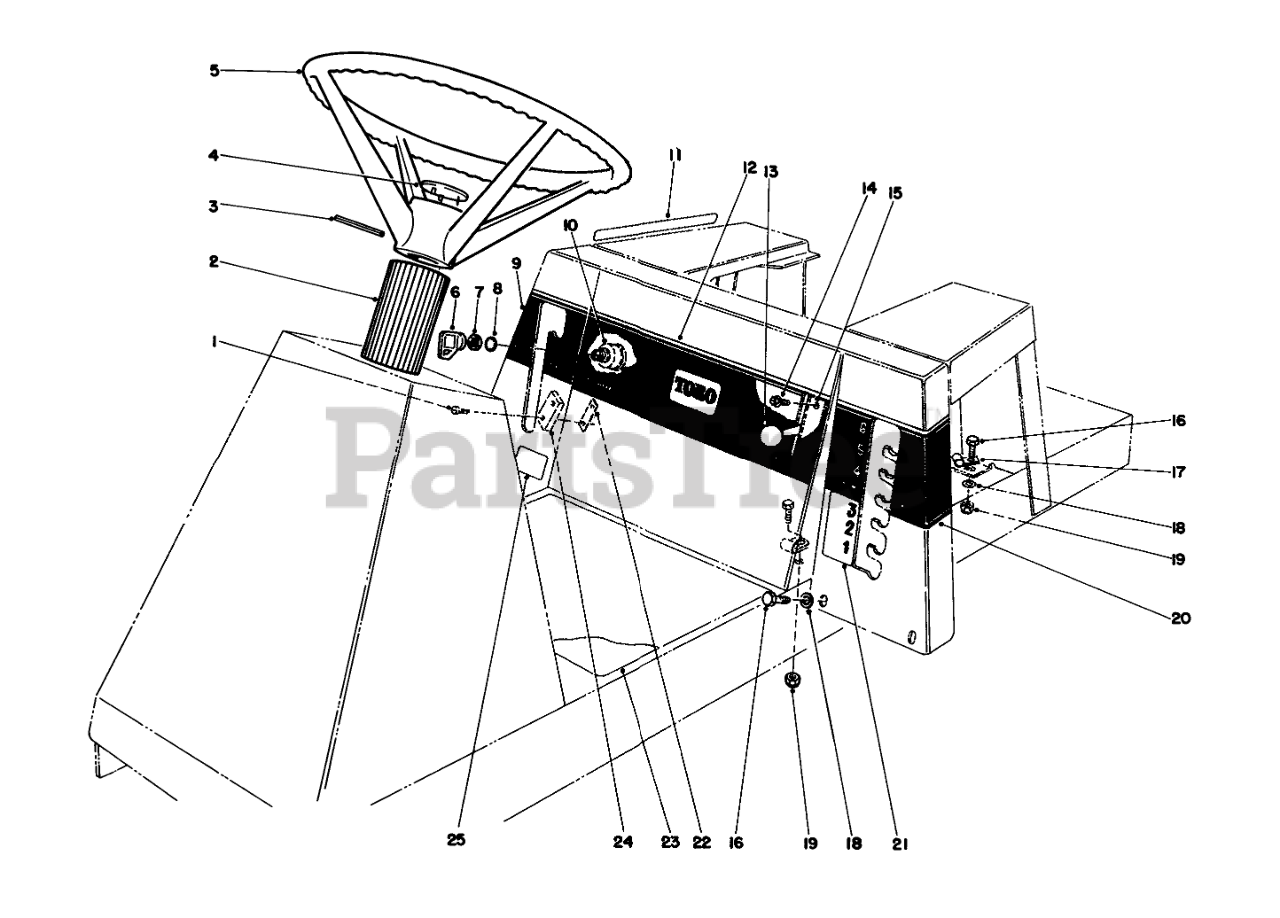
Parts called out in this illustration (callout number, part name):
1	SCREW-SPH
2	COVER-STEERING SHAFT
3	PIN-ROLL
4	STEERING WHEEL INSERT
5	Assy.-Wheel, Steering (Incl. Ref. #4)
6	KEY-IGNITION
7	NUT-HH
8	WASHER-TOOTH, INTERNAL
9	DECAL-UPPER DECK ENGAGE
10	Switch-Ignition (Incl. Ref. #6-8)
11	DECAL - SHIFT PATTERN
12	DECAL-FRT SEAT CONTROLS
13	Knob
14	SCREW-HWHTF
15	Control-Throttle (Incl. Ref. #13)
16	SCREW-HH
17	CLAMP
18	WASHER-PLAIN
19	NUT-LOCK, NI
20	DECAL - UPPER HOC
21	DECAL - LOWER HOC
22	NUT-SPEED
23	INSTRUCTION DECAL
24	SWITCH-MICRO
25	DECAL-LOWER DECK ENGAGE
